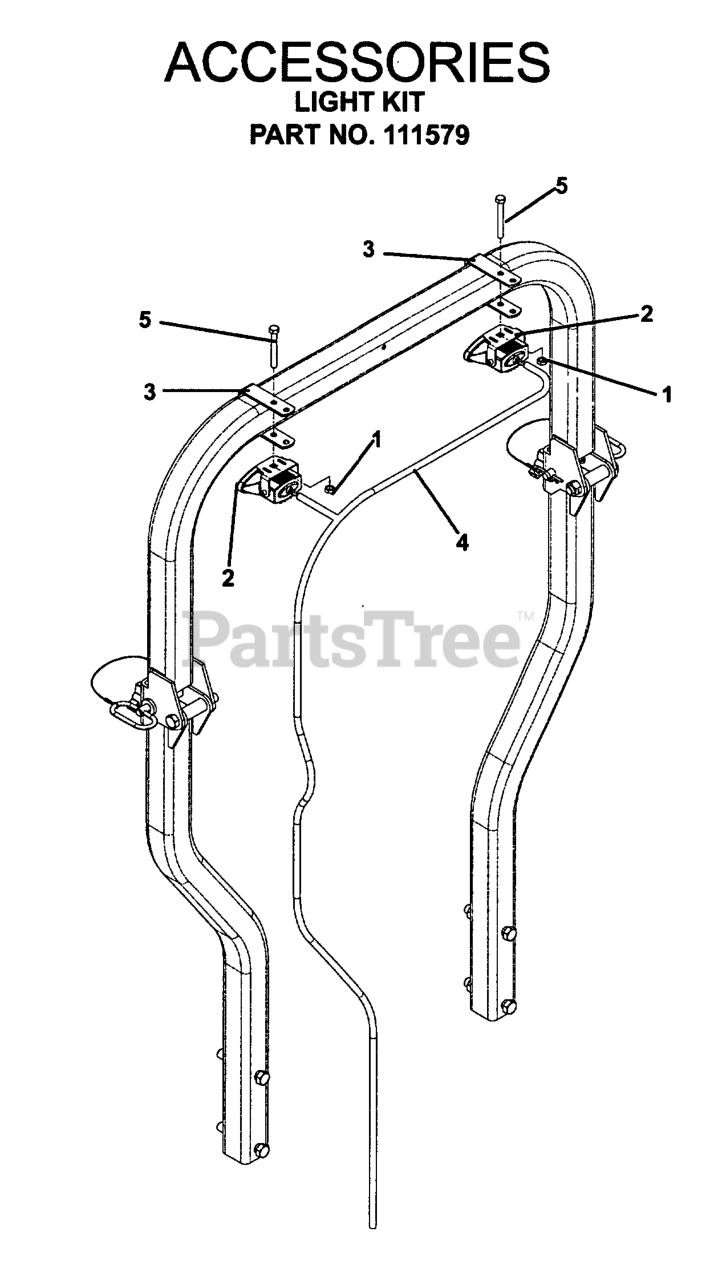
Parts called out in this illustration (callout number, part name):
1	NUT 5/16-18 HEX JAM ZD
2	LIGHT 35W W/BRKT
3	LIGHT MOUNTING BRACKET
4	LIGHT HARNESS
5	BOLT 5/16C X 2 1/2
